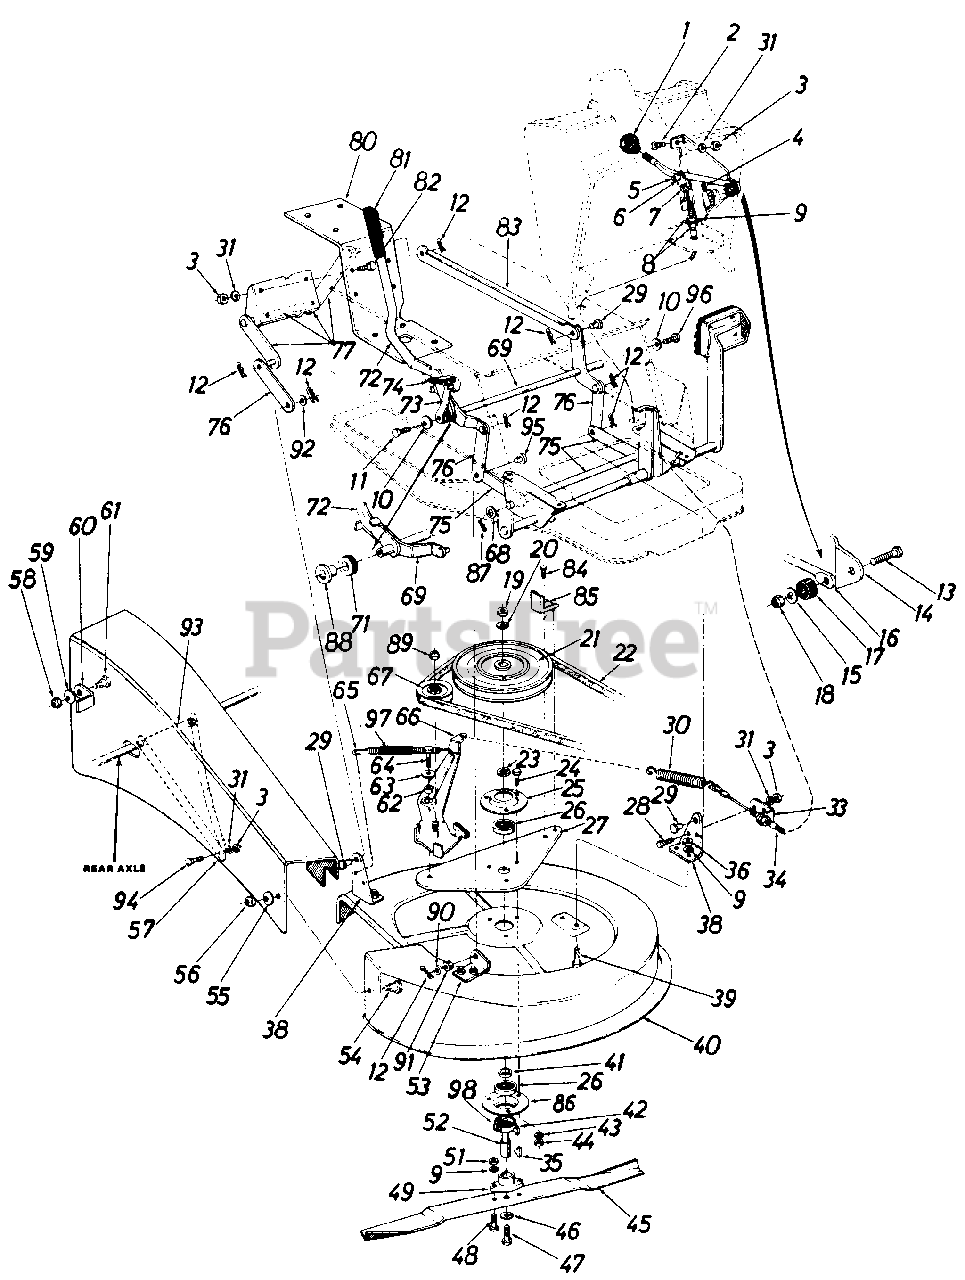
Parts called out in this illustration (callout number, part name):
1	Ball Knob
2	Truss Mach. Scr. 1/4-20 x .50" Lg.
3	Hex Nut 1/4-20 Thd.
4	Safety Switch
5	Weld Pin .250 Dia. x .62" Lg.
6	Push Cap .250 Dia.
7	Clevis
8	Hex Jam Nut 5/16-24 Thd.
9	L-Wash. 5/16" Scr.
10	Bell-Wash. .400 I.D. x 1.110 0. D.
11	Hex Wash. Hd. Self-Tap Scr. 3/8-16 x 1.25" Lg.
12	Internal Cot-Pin 1/2" Dia.
13	Hex Scr. 1/4-20 x 1.25" Lg.
14	Deck Clutch Control Brkt.
15	Fl-Wash. .280 I.D. x .750 O.D. x .063
16	Blade Clutch Lever
17	Rubber Washer
18	Hex Cent. L-Nut 1/4-20 Thd.
19	Hex Nut 5/8-11 Thd.
20	L-Wash. 5/8" Scr.
21	Deck Pulley
22	"V"-Belt "A" or 1/2" x 54" Lg.
23	Spacer
24	Hex Sems Scr. 5/16-18 x 1.99" Lg
25	Bearing Housing
26	Ball Brg. .787 I.D. x 1.850 O.D.
27	Deck Belt Guard Plate
28	Hex Sems Scr. 1/4-20 x .75" Lg.
29	Lift Brkt. Pin Special
30	Extension Spring .88 O.D. x 4.0" Lg.
31	L-Wash. 1/4" Scr.
33	Cable Bracket
34	Clutch Control Cable 26.88" Lg.
35	#6 Hi-Pro Key 5/32 x 5/8" Dia.
36	Hex Nut 5/16-18 Thd.
38	Deck Bracket
39	Carriage Bolt 5/16-18 x .75"
42	#61 Hi-Pro Key 3/16 x 5/8" Dia.
43	L-Wash. 5/16" Scr.
44	Hex Nut 5/16-18 Thd.
45	26" Blade
46	L-Wash. 3/8" Scr. H.D.
47	Hex Scr. 3/8-24 x 1.50" Lg. H .T.
48	Hex Scr. 5/16-24 x 1.00" Lg. H .T.-Spec ial
49	Blade Adapter Kit
51	Hex Nut 5/16-24 Thd.
52	Blade Spindle
53	Deck Bracket
54	Shld. Scr. .500 Dia. x .170 Lg.
55	Fl-Wash. .385 I.D. x .88 O.D.
56	Hex Cent. L-Nut 3/8-16 Thd.
57	Chute Ass'y.
58	Hex Ins. L-Nut 5/16-18 Thd.
59	Bell. Wash. .345 I.D. x .88 O.D.
60	Chute Pivot Brkt.
61	Shld. Scr. .437 I.D. x .1801' Lg.
62	Spacer .315 I.D. x .75 O.D. x .370 Lg.
63	Fl-Wash. .344 I.D. x 1.12 O.D. x .12
64	Hex Scr. 5/16-18 x 1.00" Lg.
65	Extension Spring
66	Deck Idler Brkt. Ass'y.
67	V-Idler Pulley
68	Fl-Wash. .630 I.D. x .930 O.D. x .060
69	Lift Handle Shaft Ass'y.
71	Rubber Wash.
72	Lift Handle
73	Lift Handle Stop
74	Height Adj. Knob
75	Lift Arm Shaft Ass'y.
76	Deck Link
77	Lift Pivot Brkt. Ass'y.
80	Seat Support Ass'y.
81	Grip
82	Hex Sems Scr. 1/4-20 x 1.00 Lg.*
83	Connecting Link
84	Hex Wash. Hd. Self-Tap Scr. 5/16-24 x .75" Lg.
85	Belt Keeper Ass'y.
86	Open Bearing Hsg.
87	Cotter Pin 3/32" Dia. x .75
88	Flange Brg. .62 I.D. x .87 0. D. x .63 " Lg .
89	Hex Ins. L-N ut 3/8-24 Thd.
90	Fl-Wash. .530 I.D. x .940 O.D. x .050
91	RubberWash. .531 I.D. x 1.00 O.D. x .120
92	Fl-Wash. .531 I.D. x .93 O.D. x .090
93	Chute Baffle
94	Carriage Bolt 1/4-20 x .50"
95	Clevis Pin .500
96	Self-Tap Scr. 3/16-16 x 1.0' Lg.
97	Shrink Tube
98	Bearing Shield
